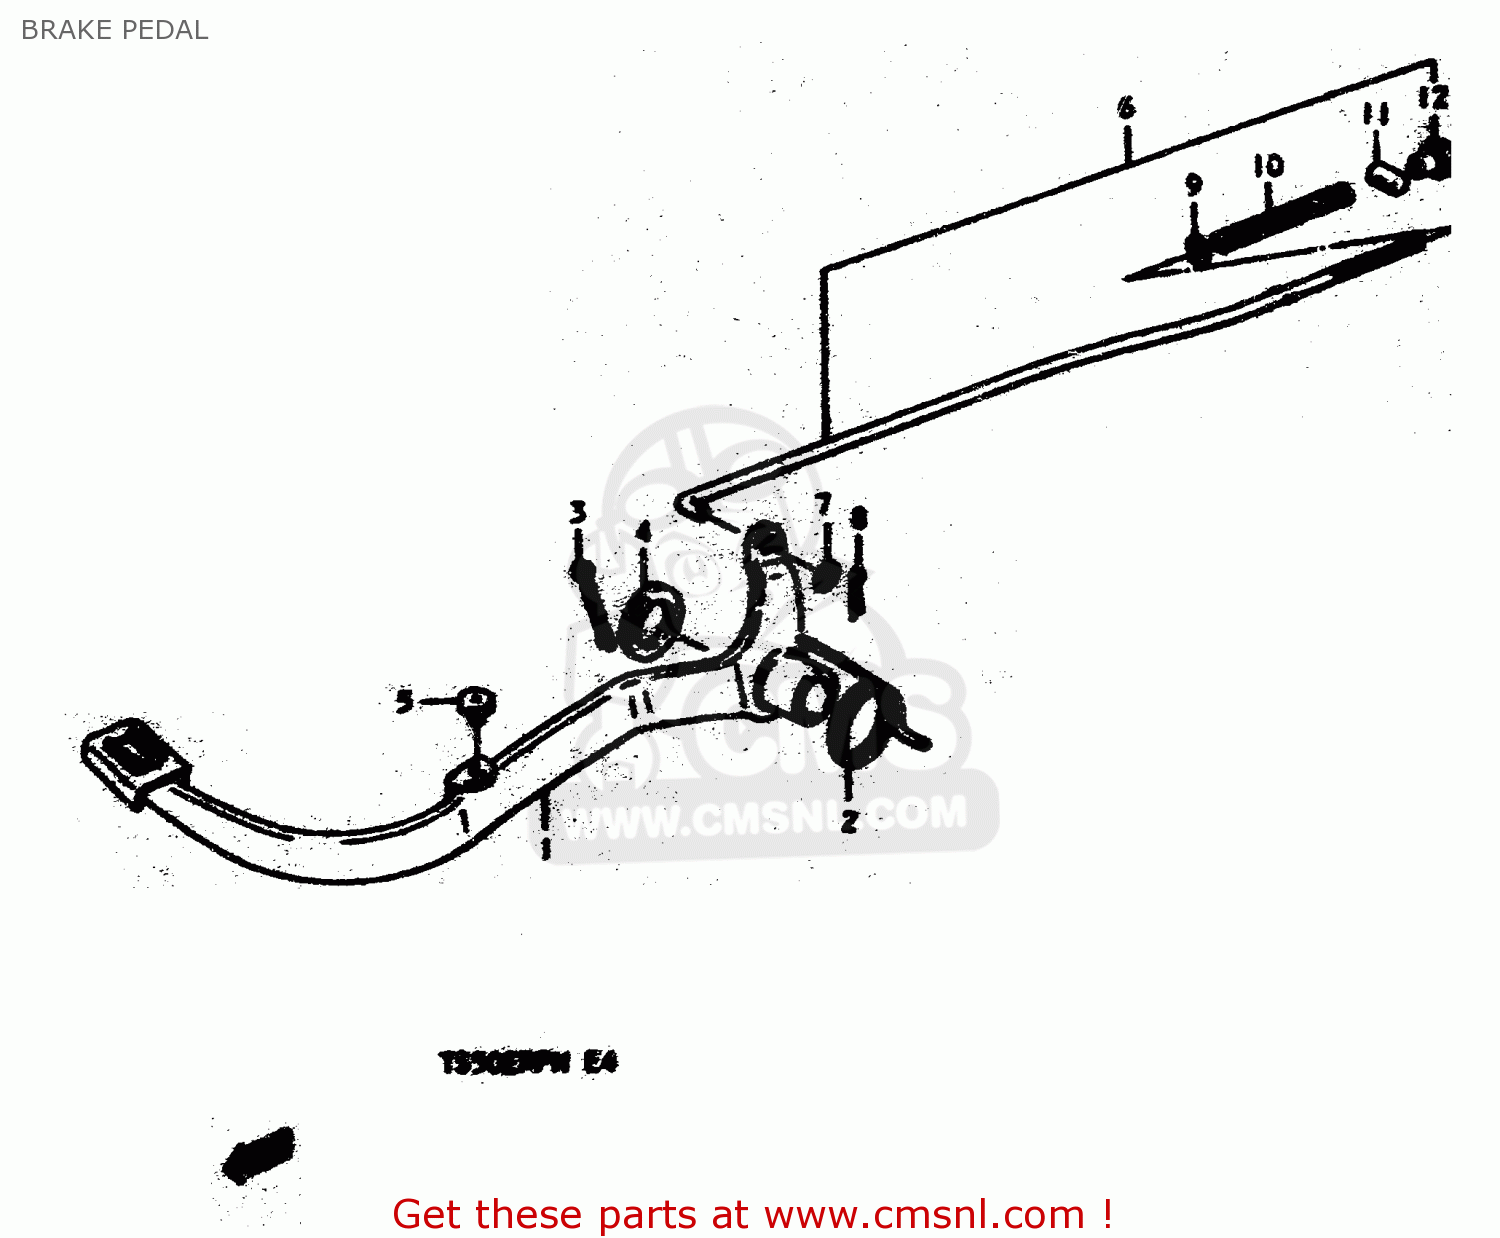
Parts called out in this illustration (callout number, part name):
1	PEDAL, BRAKE
2	SPRING
3	COTTER PIN
4	WASHER(15.5X26X2.3)
5	STOPPER,BRAKE PEDAL
6	ROD ASSY, REAR BRAKE
7	WASHER
8	PIN 20X20
9	WASHER
10	SPRING
11	PIN(11X18)
12	NUT
